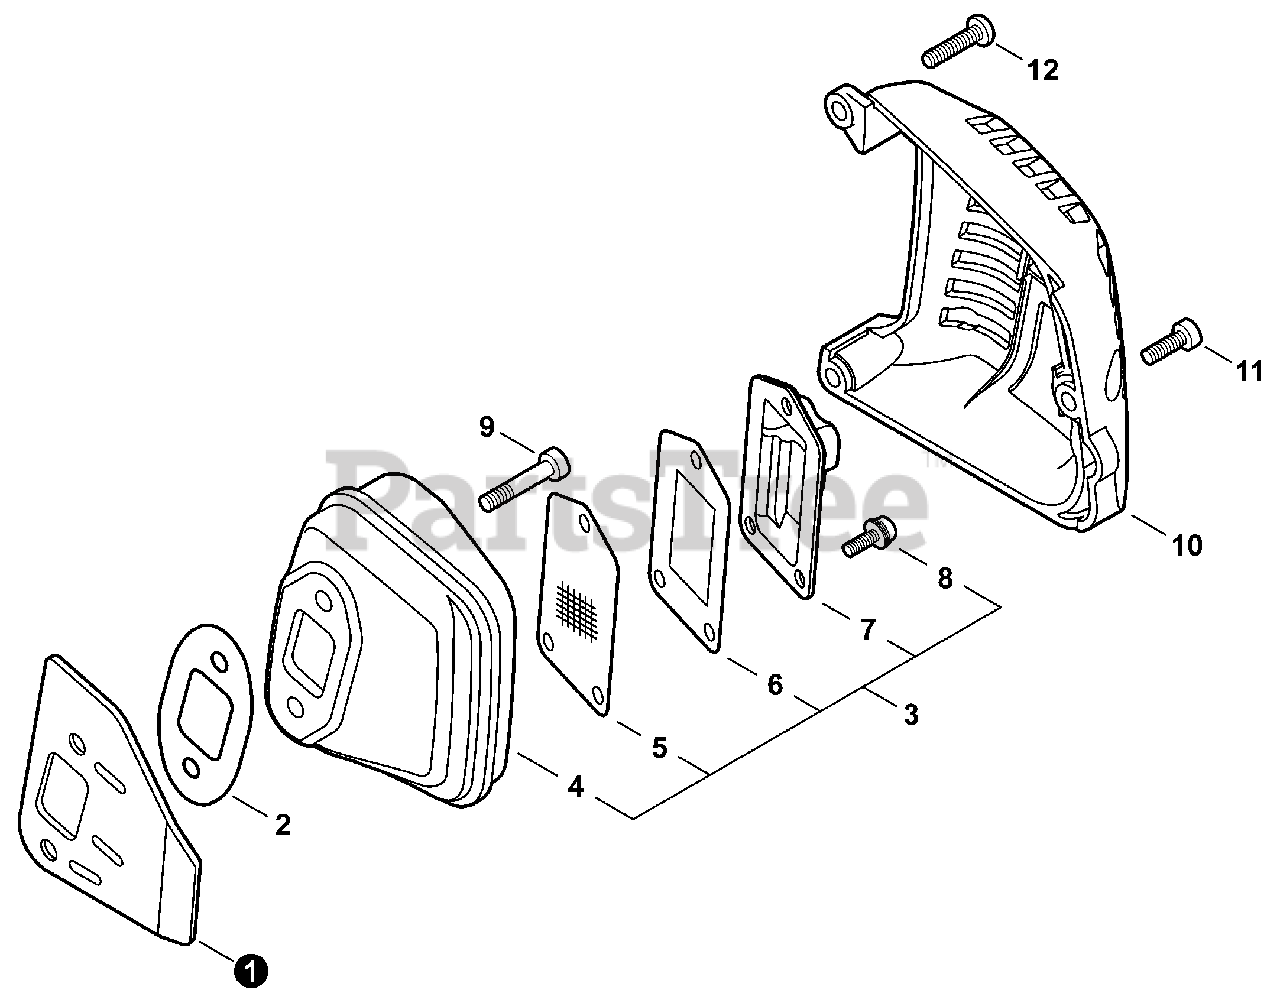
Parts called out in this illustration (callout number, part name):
1	HEAT SHIELD, EXHAUST
2	GASKET, EXHAUST
3	MUFFLER ASSY
4	MUFFLER
5	SCREEN, SPARK ARRESTER
6	GASKET, EXHAUST
7	GUIDE, EXHAUST
8	SCREW 4×10
9	BOLT, TORX 5×16
10	COVER, MUFFLER
11	BOLT, TORX 5×16
12	BOLT, TORX 5×20
